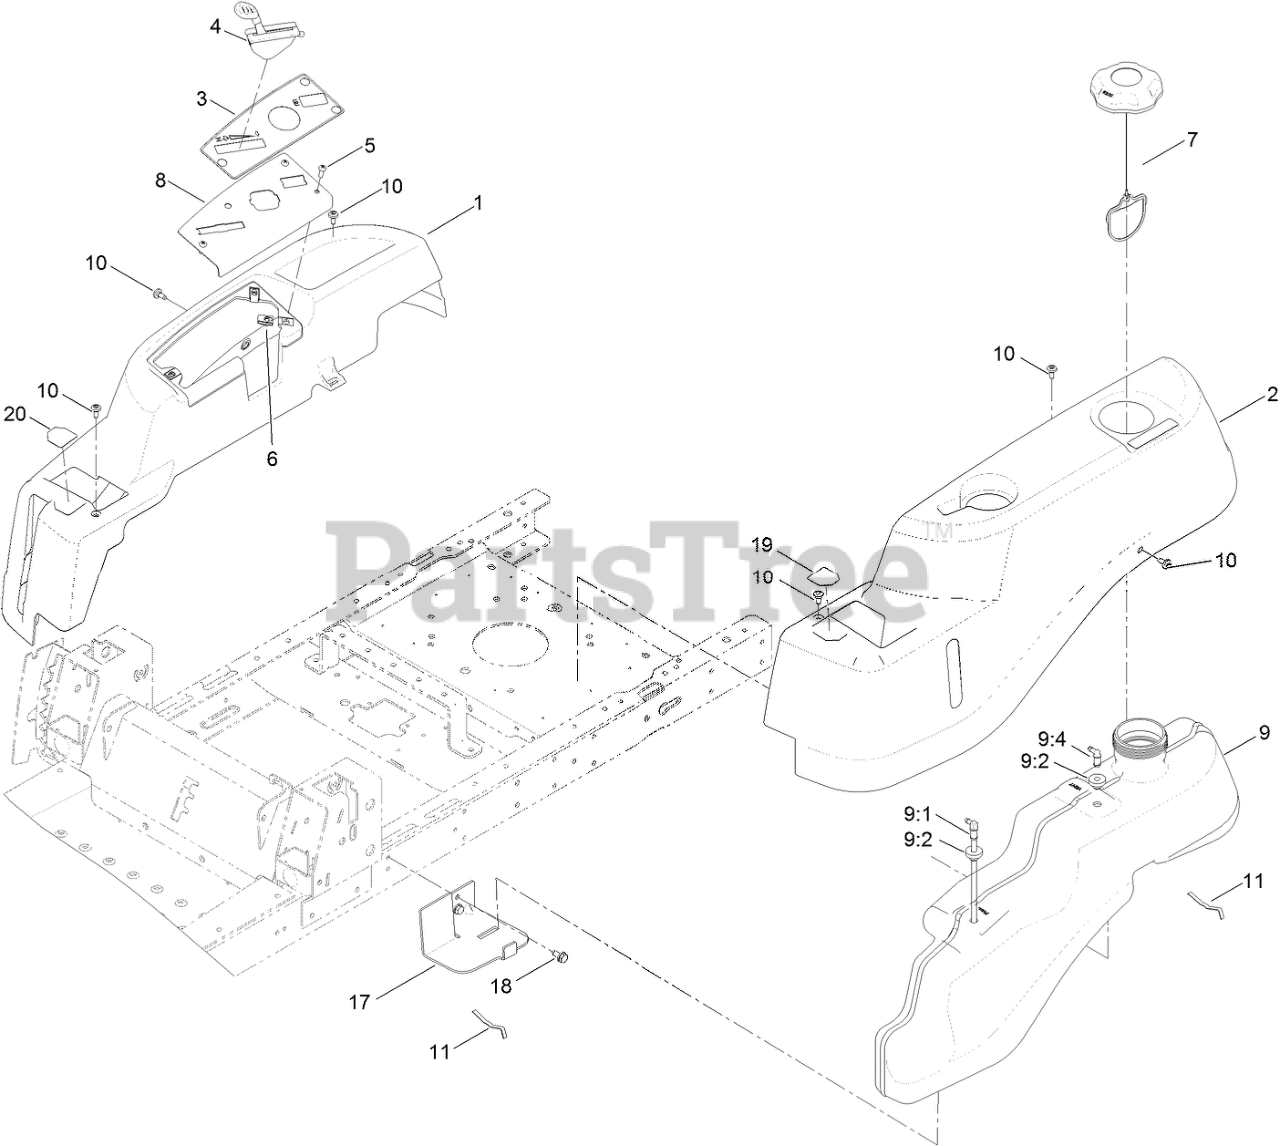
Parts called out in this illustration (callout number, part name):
1	POD-RH
2	POD-LH
3	DECAL-PANEL, CONTROL
4	CABLE-THROTTLE AND CHOKE
5	SCREW-PRH
7	CAP-FUEL, RATCHETING
8	PLATE-CONTROL
9	FUEL TANK ASM
9:1	CONNECTOR-ELBOW, 90 DEG
9:2	BUSHING
9:4	FITTING-PLASTIC
10	SCREW-SHOULDER
11	SPRING
17	SUPPORT-TANK, FRONT
18	SCREW-HWHTF
19	DECAL-CONTROL LEVER, LH
20	DECAL-CONTROL LEVER, LH
